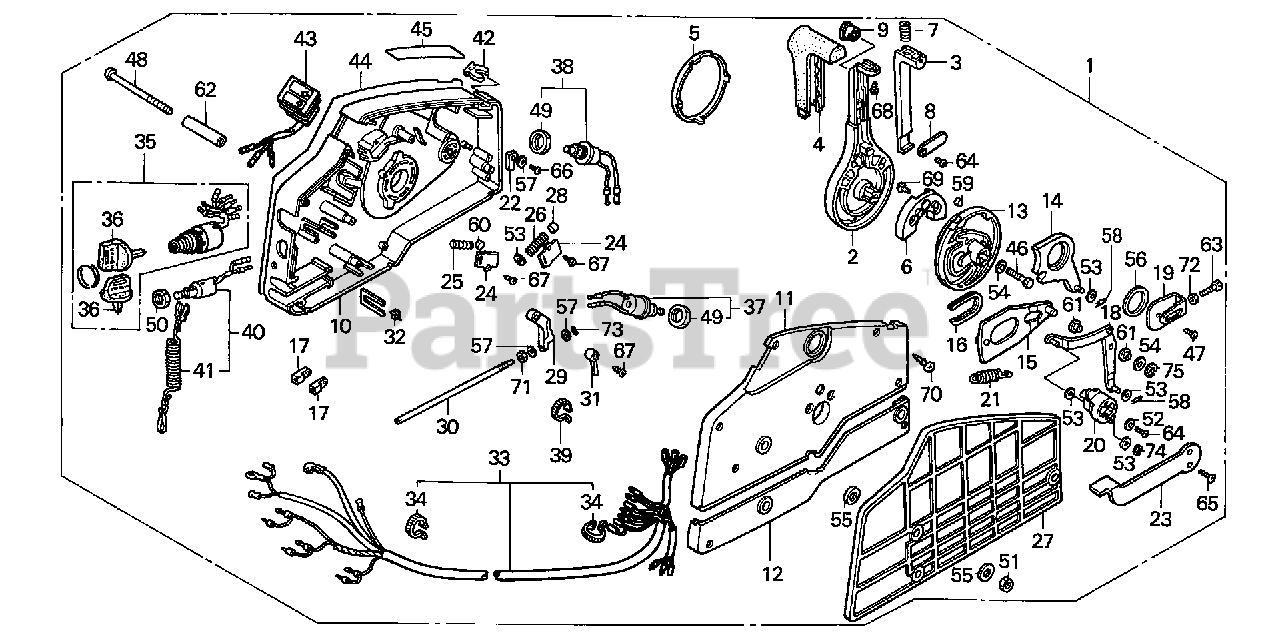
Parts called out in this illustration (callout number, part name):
1	BOX ASSY., REMOTE CONTROL
2	HANDLE, REMOTE CONTROL
3	LEVER, HANDLE LOCK
4	GRIP, REMOTE CONTROL HANDLE
5	CAP, HANDLE
6	BLOCK, NEUTRAL LOCK
7	SPRING, REMOTE CONTROL HANDLE
8	PLATE, LEVER SETTING
9	COVER, GRIP
10	HOUSING, REMOTE CONTROL BOX (A)
11	HOUSING, REMOTE CONTROL BOX (B)
12	HOUSING, REMOTE CONTROL BOX (C)
13	WHEEL, CONTROL
14	ARM, SHIFT LINK
15	PLATE, SLIDING
16	COLLAR, SLIDING PLATE
17	PIVOT, SHIFT
18	ARM, LINK JOINT
19	BRACKET, LINK JOINT
20	WHEEL, ACCELERATOR
21	SPRING, ACCELERATOR WHEEL
22	CAM, STARTER SWITCH
23	LEVER, IDLE
24	PLATE, SPRING SETTING
25	SPRING, SHIFT CLICK
26	SPRING, CHOKE RETURN
27	SPACER, REMOTE CONTROL BOX
28	SPACER, CLICK SPRING
29	BLOCK, THROTTLE FRICTION
30	BOLT, FRICTION
31	SPACER, NEUTRAL SWITCH
32	SPACER, CABLE CLAMP
33	CABLE ASSY., REMOTE CONTROL
34	TIE, CABLE (2.4X92) (NATURAL)
35	SWITCH ASSY., COMBINATION
36	KEY ASSY., COMBINATION SWITCH
37	SWITCH ASSY., THROTTLE
38	SWITCH ASSY., SOLENOID
39	BAND (BLACK 3.5X140)
40	SWITCH ASSY., EMERGENCY STOP
41	WIRE, EMERGENCY
42	CLIP, EMERGENCY LOCK
43	LAMP ASSY., INDICATOR
44	PLATE, REMOTE CONTROL (J,E,EF)
45	MARK, FAST IDLE
46	BOLT, HEX. (8X35)
47	SCREW, PAN (6X10)
48	SCREW (6X95)
49	NUT, HEX. (20MM)
50	NUT, HEX. (16MM)
51	NUT, HEX. (6MM)
52	WASHER, PLAIN (5MM)
53	WASHER, THRUST (51MM)
54	WASHER, PLAIN (8MM)
55	WASHER (6MM)
56	WASHER (28MM)
57	WASHER, PLAIN (4MM)
58	PIN, LOCK (6MM)
59	PIN (6X6)
60	ROLLER, CLICK
61	COLLAR, LINK JOINT
62	COLLAR, DISTANCE (6X10X43.5)
63	BOLT, HEX. (5X20)
64	SCREW, PAN (5X10)
65	SCREW, OVAL (5X12)
66	SCREW, TAPPING (4X10)
67	SCREW, TAPPING (5X10)
68	SCREW, TAPPING (5X12)
69	SCREW, TAPPING (6X16)
70	SCREW, TAPPING (5X25)
71	NUT, HEX. (6MM)
72	NUT, HEX. (5MM)
73	E-RING (3MM)
74	E-RING (4MM)
75	E-RING (7MM)
